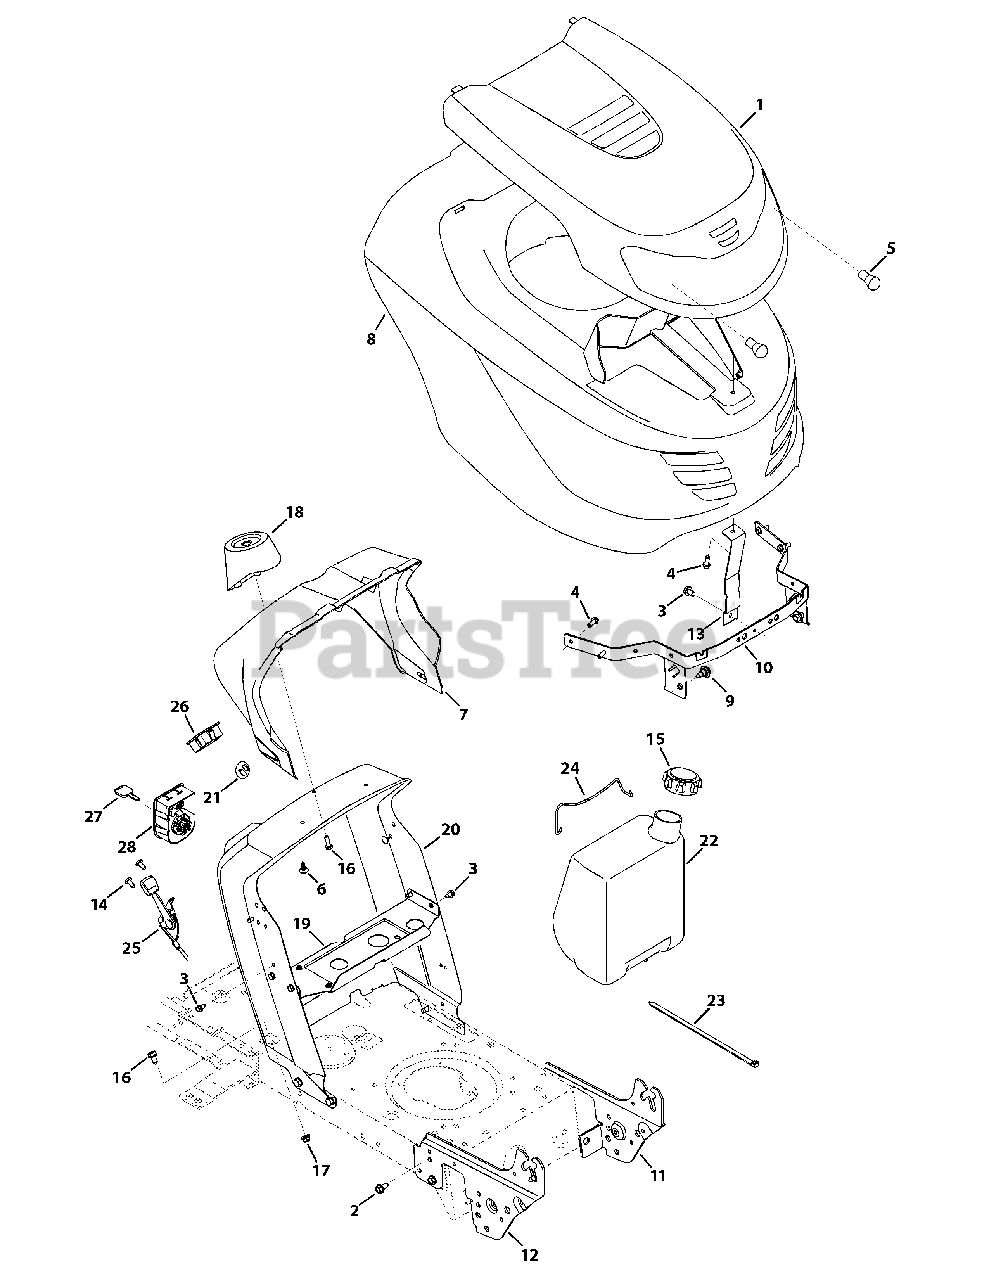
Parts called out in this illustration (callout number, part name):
1	Grille Style G
2	S-Tapp Scr 5/16-18 x .75
3	Hex Wash S-Tapp Scr 1/4-20 x .50
4	Hex Tapp Scr 1/4 x .75" Lg.
5	Miniature Lamp 12V Socket Type
7	Dash Collar
9	Shoulder Screw 5/16-18, .43 x .29
10	Pivot Hood Bracket
12	RH Pivot Bracket
13	Hood Support Bracket
14	Hex Wash Hd Scr. 1/4-20 x .500
15	Cap-Fuel
16	Hex Tapp Scr 1/4 x .75" Lg.
17	Flange Locknut 5/16-18 Gr. F, Nylon
18	Steering Support
19	Gas Tank Support Bracket
20	Dash Assembly
22	Fuel Tank 1.5 gal.
25	Choke/Throttle Cable
26	Indicator Monitor
28	Key Switch Module
30	Shoulder Scr. .498 x .340: 3/8-16
31	Hex L-Nut 3/8-16 Gr. B
